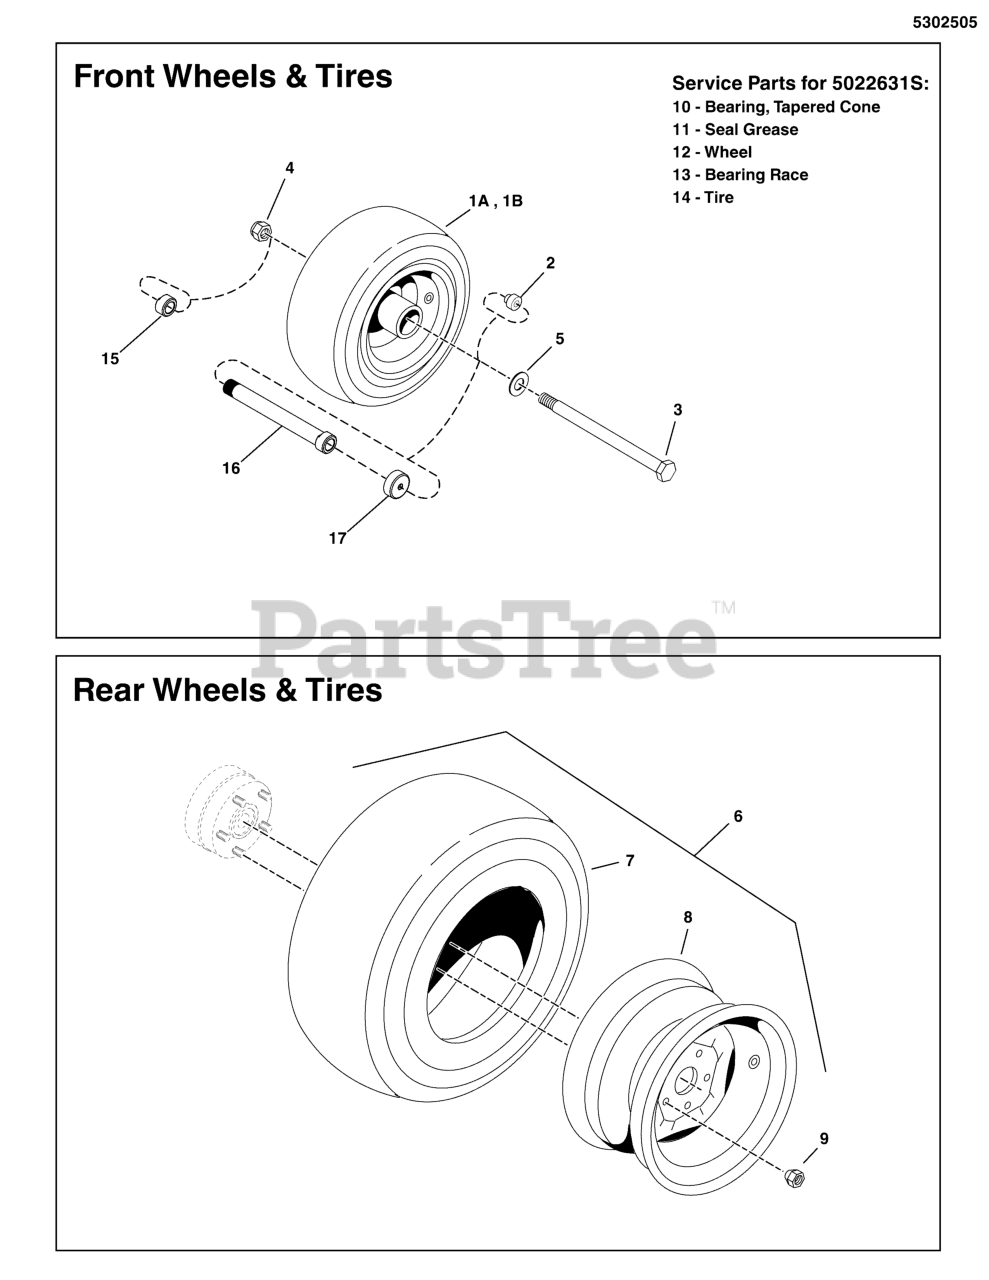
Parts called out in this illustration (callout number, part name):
2	ADAPTER, CASTER AXLE, CZ
3	BOLT, 1/2-13 x 8"
4	NUT, Hex Flange, Nylock, 1/2-13
5	WASHER, 1/2 SAE
6	TIRE ASSM, 22X11.00-10, .75 NEG
7	TIRE, 22 X 11.00-10, 4 PLY
8	WHEEL, 10 X 7, .75NEG OFFSET
9	NUT, 1/2-20, FOR WHEEL BOLT SILVER
10	BEARING, Tapered Roller
11	SEAL, GREASE
12	WHEEL ASSY, 13 X 5 X 6, SILVER
13	BEARING, RACE
14	TIRE ONLY
15	NUT, BEARING ADJUSTER, AXLE
16	BEARING ADJUSTER, SPACER, 6.062 LG
17	DEBRIS COVER, CASTER WHEELS
